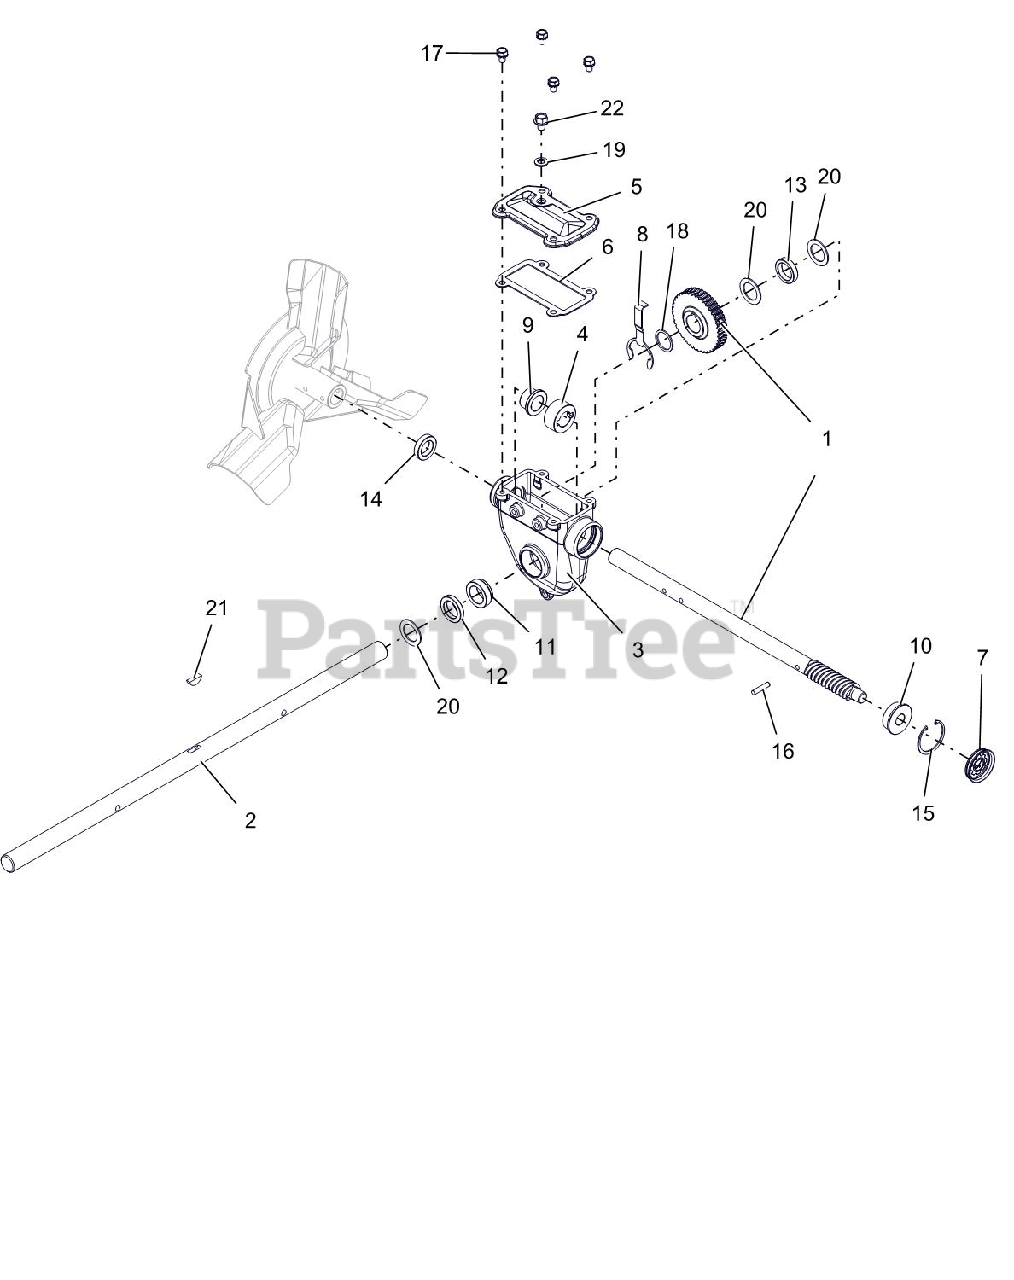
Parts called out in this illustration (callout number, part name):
1	ASSY, WORM SHAFT & GEAR
2	SHAFT, RAKE-28"
3	GEARCASE, LARGE MACHINED
4	THRUST COLLAR, .875"ID SLIPFIT
5	COVER, TOP - LARGE IRON
6	GASKET, TOP - LARGE GEARCASE
7	COVER, GEAR CASE 1.75"
8	BUSHING RETAINER, LARGE
9	BSHG-FLG .879X1.128X.75X1.45
10	BSHG-FLG .628X1.503X.58X1.725
11	BSHG-FLG LARGE, RIGHT
12	SEAL-OIL .999X1.500X.250 TBC29
13	SEAL-OIL .999X1.375X.312 TBC29
14	SEAL-OIL .873X1.375X.312 TBC29
15	RG-RTNG-INT 1.750X.062
16	PIN-STR .250X1.12 6150
17	BOLT, SEMS .31-18X.50 GR5 YWZC
18	WSHR-FL-STL 1.010X1.250X.068YZ
19	WSHR-BND-SEAL .38X.75X.11 GALV
20	WSHR-FL-STL 1.010X1.505X.062YZ
21	KEY-WDRF .25X.875 HRD #A
22	@SCR-ROLOK .38-16X.50 HWH YWZC
